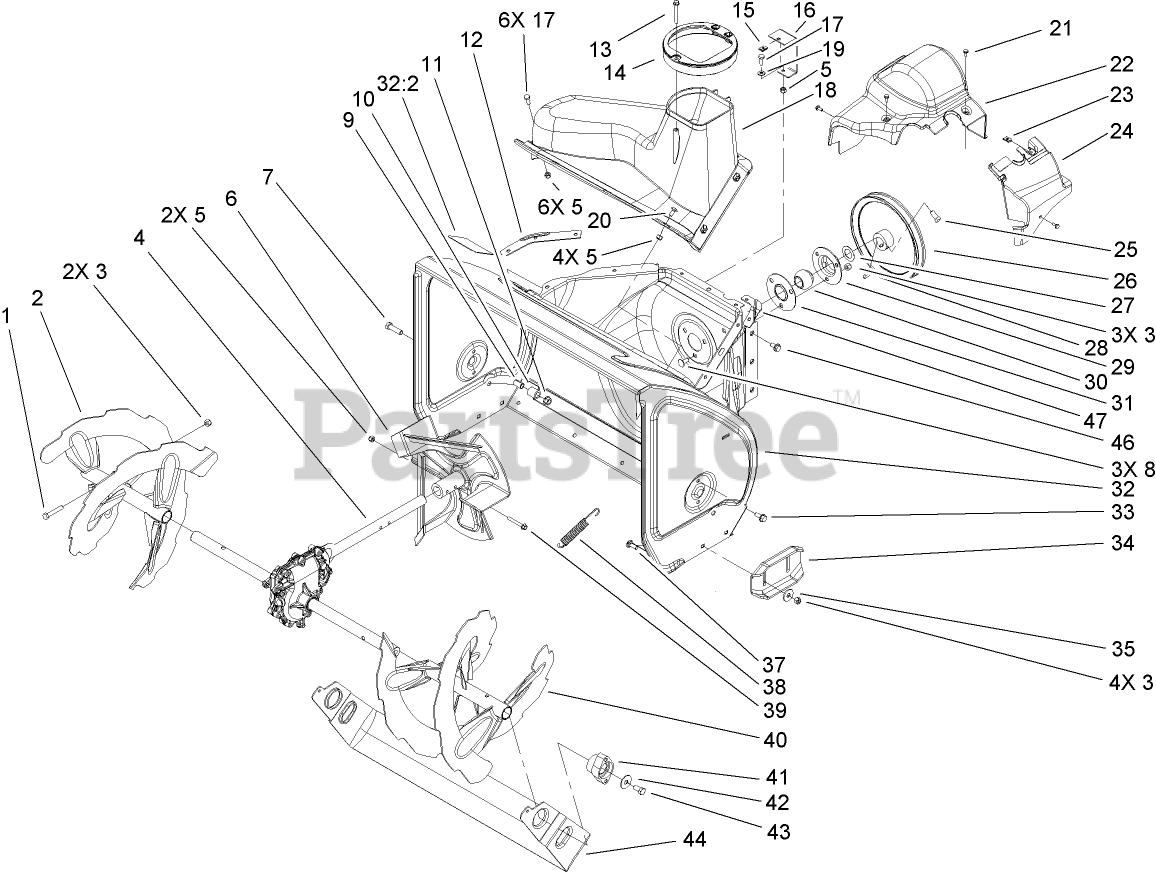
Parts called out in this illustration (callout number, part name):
1	SCREW-HH
2	RH AUGER ASM
3	NUT-LOCK, NI
5	NUT-LOCK, NI
6	IMPELLER ASM
7	SCREW-HH
8	SCREW-CARR
9	SPACER-SCRAPER, STOP
10	CUSHION-SCRAPER, STOP
11	NUT-HF
12	SEAL-FLANGE, COVER
13	SCREW-PLASTITE
14	GUIDE-CHUTE
15	NUT-SPEED
16	BRACKET-COVER, CLIP NUT
17	SCREW-HH
19	WASHER-FLAT
20	BOLT-CARR
21	SCREW-HWH
23	NUT-SPEED
24	COVER-EXTENSION, BELT
25	SCREW-SET, SQH
27	WASHER-THRUST
28	KEY-WOODRUFF
29	FLANGE-CUP, BEARING
30	BEARING-BALL
31	FLANGE-CUP, BEARING
32	HOUSING-AUGER, 28 INCH
33	SCREW-HWHTF
35	WASHER
37	SCREW-CARR
38	SPRING-SCRAPER
39	SCREW-HHF
40	LH AUGER ASM
41	BEARING-AUGER
42	WASHER
43	SCREW-HH
44	SCRAPER-PIVOTING, 28 INCH
46	SCREW-HWHTF
